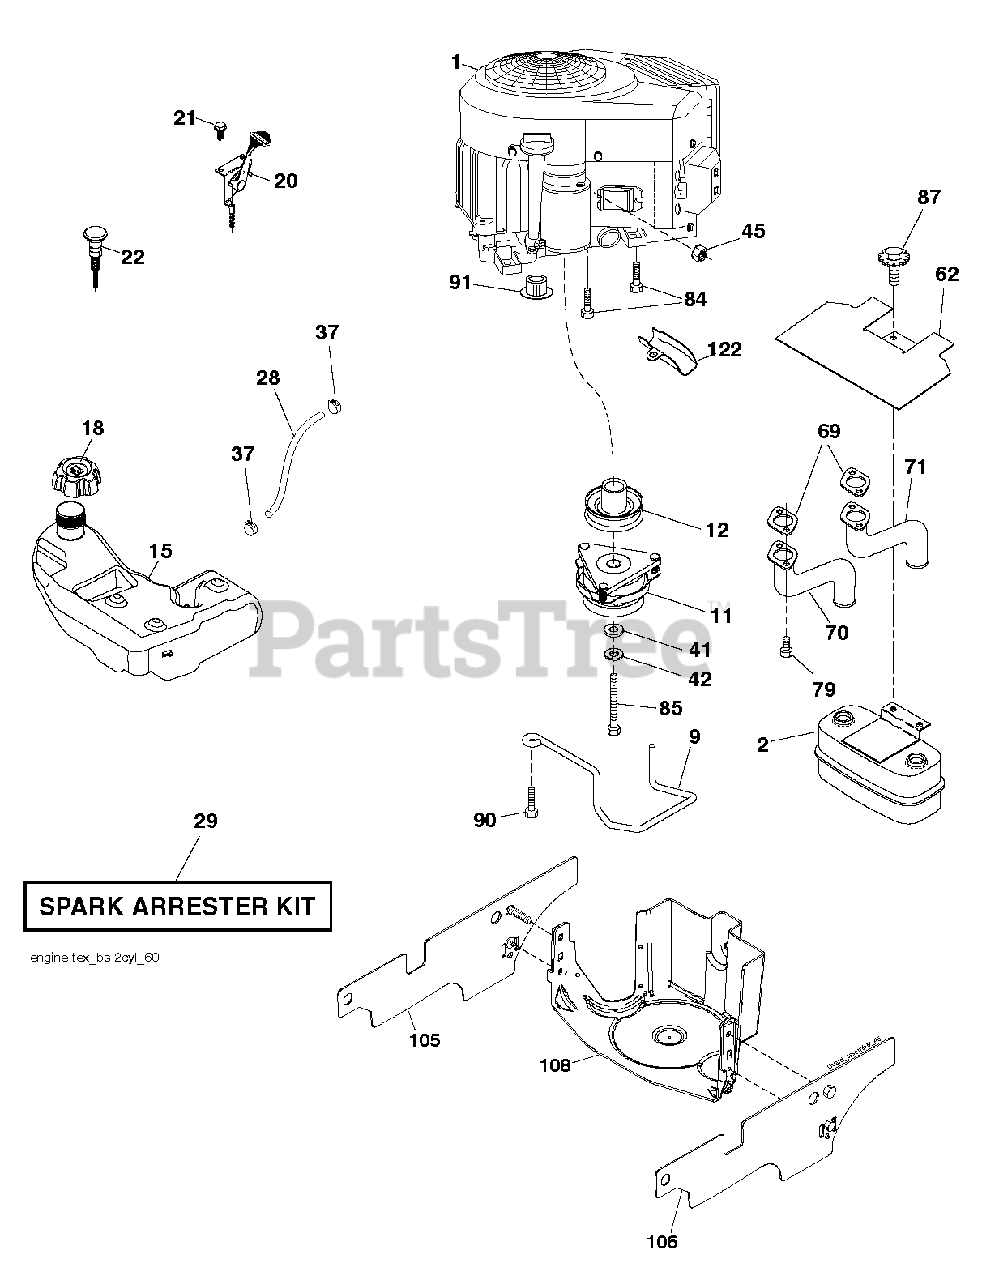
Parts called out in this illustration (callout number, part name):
2	MUFFLER.TWIN.CYL.LOW.TONE
9	KEEPER.BELT.ENGINE.4.2
11	CLUTCH
12	PULLEY.ENGINE.TUFFTORQ
15	TANK.FUEL.4GAL
18	CAP.ASM.FUEL.TANK.3"BLACK
20	THROTTLE CABLE
21	SCREW.#10 X 0.750.BOS THREAD
22	CONTROL CHOKE
28	LINE.FUEL.20
29	ARRESTER SPARK (OPTIONAL)
37	HOSE CLAMP
42	LOCKWASHER
45	NUT
62	SHIELD.HEAT.MUFFLER
69	GASKET.MUFFLER
70	TUBE MANIFOLD LH
71	EXHAUST TUBE RH
79	SCREW.SOCKET.HEAD.5/16-18
84	SCREW.3/8-16
85	BOLT HEX 7/16-20X4-1/4"
87	BOLT, 5/16-18 X 1 3/4
90	SCREW 3/8-16X1
91	BUSHING.1.375OD
122	EXTENSION DRAIN OIL
